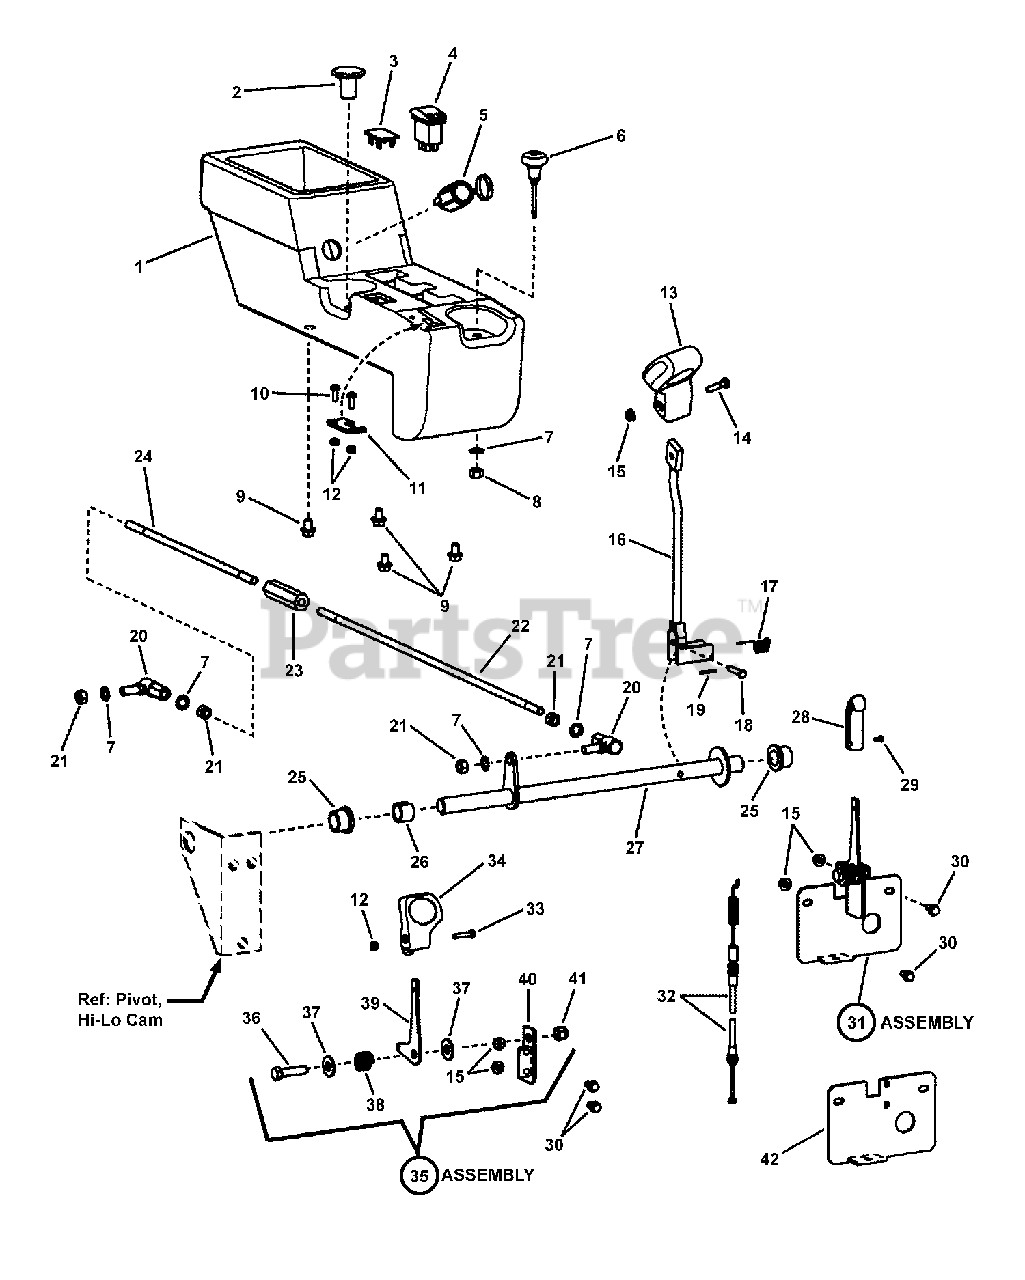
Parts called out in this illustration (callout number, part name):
1	CONSOLE, UV-2
2	KNOB, Park Brake, Red
2	KNOB, Parking
3	PLUG, Dash Hole
4	SWITCH, Momentary Rocker (On-Off-On)
5	OUTLET, 12 Volt DC Power
6	CABLE, Choke, B&S 16HP Vanguard
7	WASHER, 3/8" Internal Tooth Lock
8	NUT, 3/8-24 Hex, GR B
9	BOLT, 5/16-18 x 1/2" Hex Flange Lock
10	SCREW, #10-32 x 5/8" Hex Washer Head Machine
11	CONTACT PLATE, Differential Lock
12	NUT, #10-32 Hex Nyloc
13	HANDLE, Shift
14	SCREW, 1/4-20 x 1" Hex Head Cap, GR 5
15	NUT, 1/4-20 Hex Flange Lock, GR 5
16	WELDMENT, Shift Rod
17	SPRING, Transmission Extension (Short)
18	CLEVIS PIN, 1/4 x 1-1/4"
19	COTTER PIN, 3/32 x 3/4"
20	BALL JOINT, 3/8-24 Thread
21	NUT, 3/8-24 Hex, GR B
22	ROD, CVT Shift, 21-5/8" Long (3/8-24 thread- both ends)
23	HEX BLOCK, Shift Adj. (3/8-24 thread, LH & RH)
24	ROD, CVT Shift, 12-1/8" Long (3/8-24 thread, LH & RH)
25	BEARING, .750 I.D.
26	RING, Rear Lift Arm- Blue
27	WELDMENT, Trans. Shifter (9.44" inside measure)
28	LEVER, Throttle Control
29	RIVET, Plastic Snap
30	SCREW, 1/4-20 x 1/2" Hex Flange Lock, GR 5
31	ASS'Y, Differential Lock (incl. items 11, 15, 30, 35 & 42)
31	ASSEMBLY, Differential Lock (Camo version)
32	CABLE, Differential Lock
33	* SCREW, Hex Washer Head Slot #10 x 1"
34	* KNOB, Throttle (Red)
35	ASSEMBLY, Differential Lock (Includes next 6 items)
36	SCREW, 3/8-16 x 1-1/2" Hex Head Cap, GR 5
37	WASHER, 3/8" SAE Flat
38	SPRING, Friction Pack
39	LEVER, Differential Lock
40	BRACKET, Differential Lock
41	NUT, 3/8-16 Hex Nyloc
42	MOUNTING PLATE, Differential Lock
